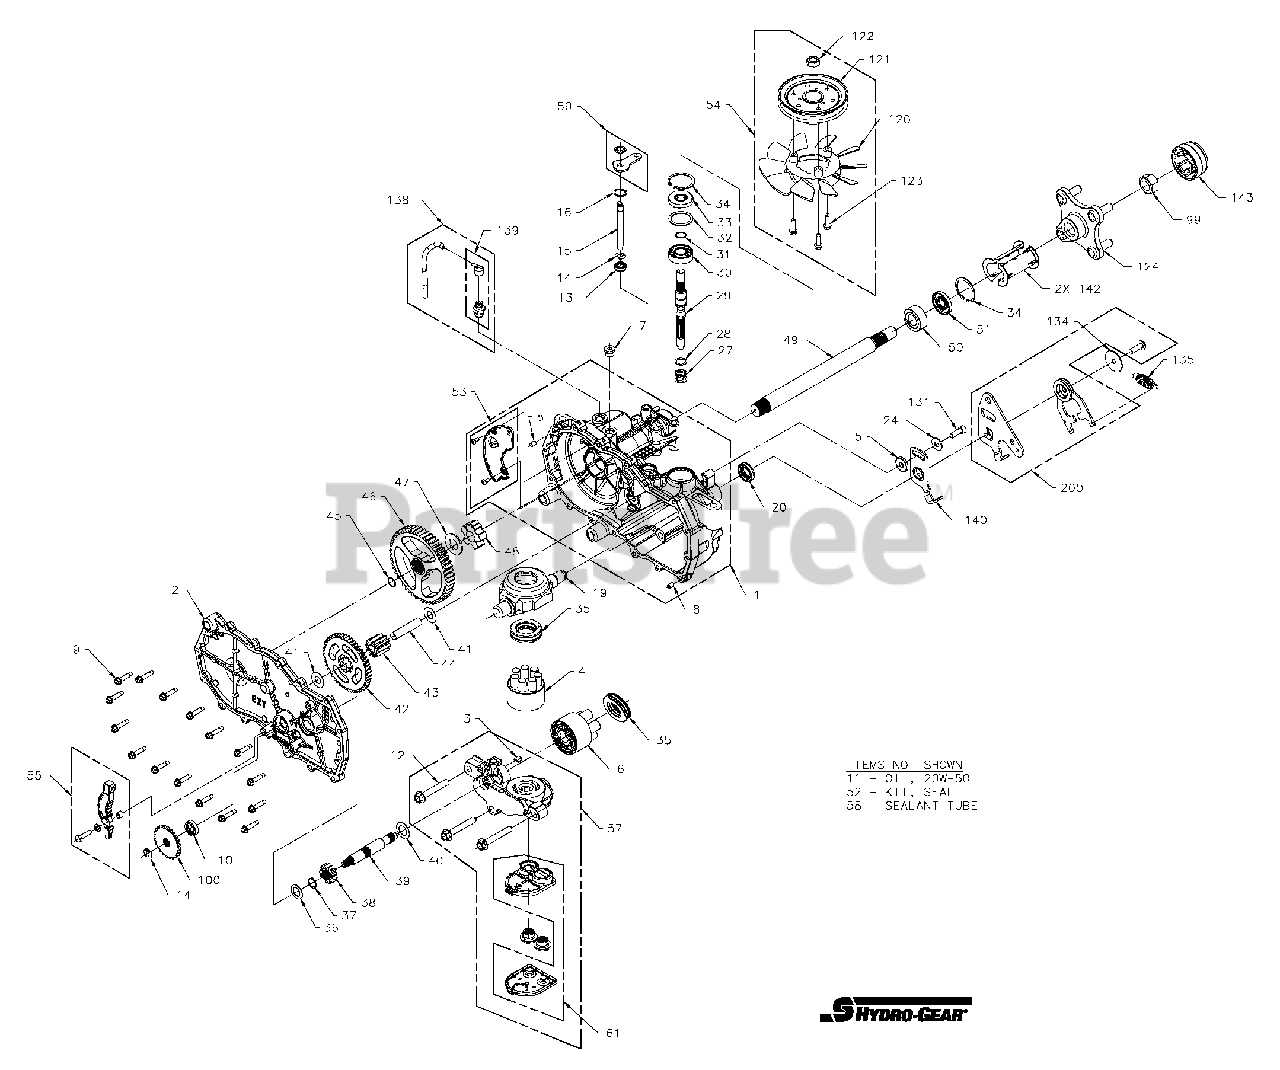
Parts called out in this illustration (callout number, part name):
1	ASSEMBLY, MAIN HOUSING-LH
2	ASSEMBLY, SIDE-LH
3	PLATE, BYPASS
4	ASSY, BLOCK 7 PISTON
6	KIT, 10 CC BLOCK
8	PIN, STAINLESS, HEADLESS
9	HFHCS 1/4-20 X 1.25 (SELF-TAPPING)
10	KIT, SEAL
13	SEAL, LIP .375X.75X.25
14	RING. RETAINING
15	ROD, BYPASS
16	RING, RETAINING .750 INT
19	TRUNNION, SWASHPLATE
27	SPRING-HELICAL COMPRESSION
28	WASHER. THRUST .59 X .79 X .04
29	SHAFT, INPUT
30	BRG, BALL 17X40X12
31	RING, RETAINING WIRE .561 ID
32	SPACER
34	RING, RET 1.56 INT
35	BEARING. THRUST 30 X 52 X 13
37	RING, RETAINING
39	SHAFT, MOTOR
41	WASHER .5X1.0X.032
43	GEAR, 10T JACKSHAFT
44	PIN, JACKSHAFT
45	RING, RET - SPIRAL
46	GEAR, 52T BULL
48	BEARING, SLEEVE (INBOARD)
49	SHAFT, AXLE
50	BUSHING, SLEEVE
51	SEAL, LIP .750 X 1.577 X
52	KIT, SEALS AND RETAINING
53	KIT, EXPANSION PLATE, LH
54	KIT, FAN-PULLEY
55	BRAKE ARM, EZT #70865
58	SEALANT TUBE 10.1OZ.
59	KIT, BYPASS ARM
61	KIT, FILTER
99	NUT, HEX, LOCK 3/4-16
100	DISC, COG BRAKE
120	FAN, 7", 10 BLADE
121	FAN PULLEY KIT 4.5X1.625
124	KIT, HUB 1/2-20
131	SHCS, 5/16-24 X 1.00 (PATCH)
134	WASHER
135	SPRING, EXTENSION
138	KIT, BREATHER ASSEMBLY
139	KIT, BREATHER
140	ARM, NEUTRAL - LH
142	TUBE, AXLE, 2.86, SPLIT
143	CAP, AXLE
200	KIT, RTN ASSEMBLY, LH
